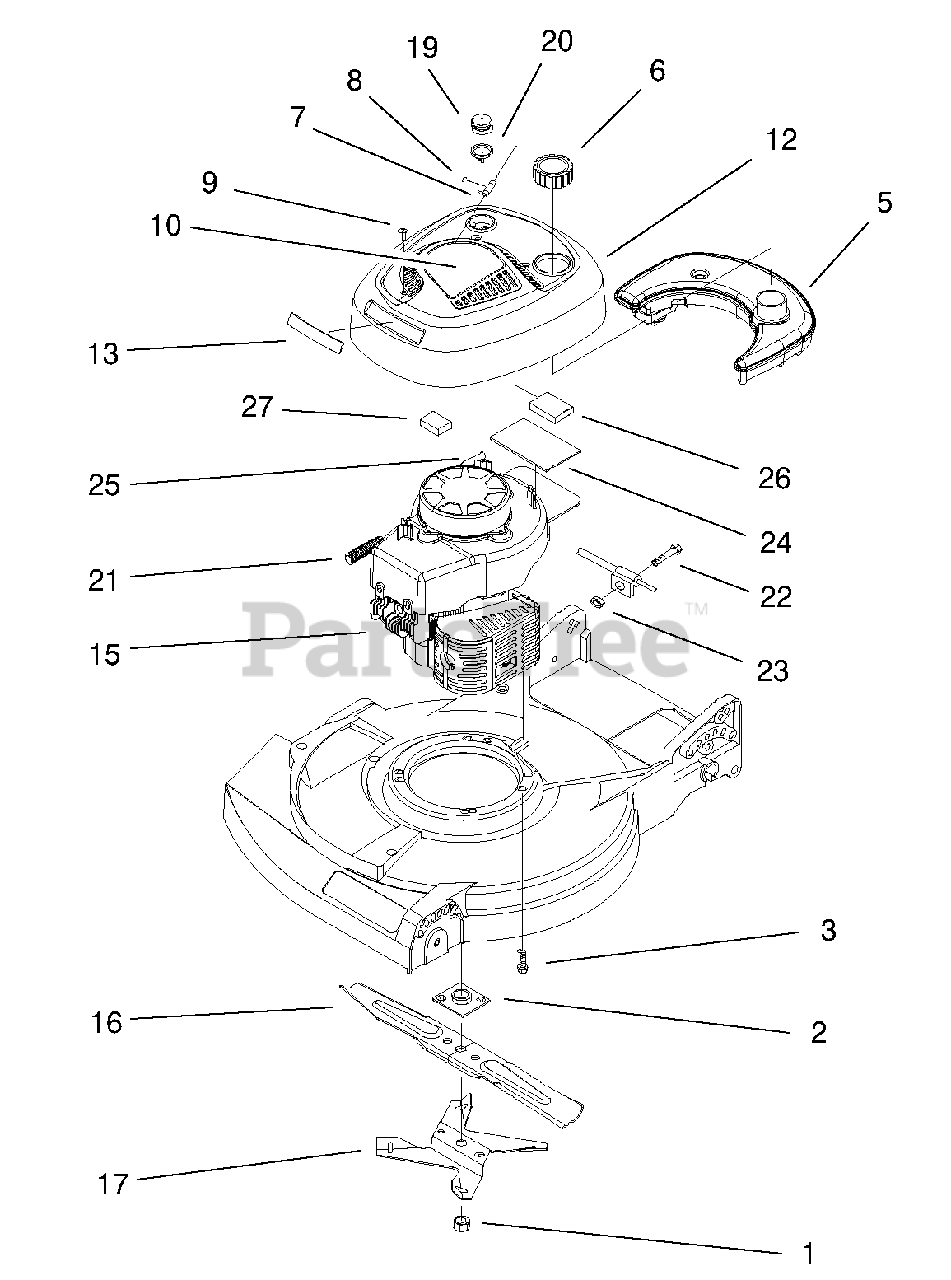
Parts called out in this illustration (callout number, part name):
1	Nut-Blade
2	Plate & Collar ASM
3	Screw-Sems
6	Cap ASM-Fuel & Oil
7	Stop-Rope
8	Staple (Obtain Locally)
9	Screw-Pan Sems
10	Decal-Recoil
12	Shroud & Recoil Cover ASM
13	Applique-Shroud
15	Engine ASM
16	Blade
17	Fan-Mulching
19	Bulb-Primer
20	Body-Primer
21	Spring-Compression
22	Screw-Throttle Cable
23	Nut-Throttle Cable
24	Pad-Foam
25	Fuel Line
26	Strip-Foam
27	Strip-Foam
